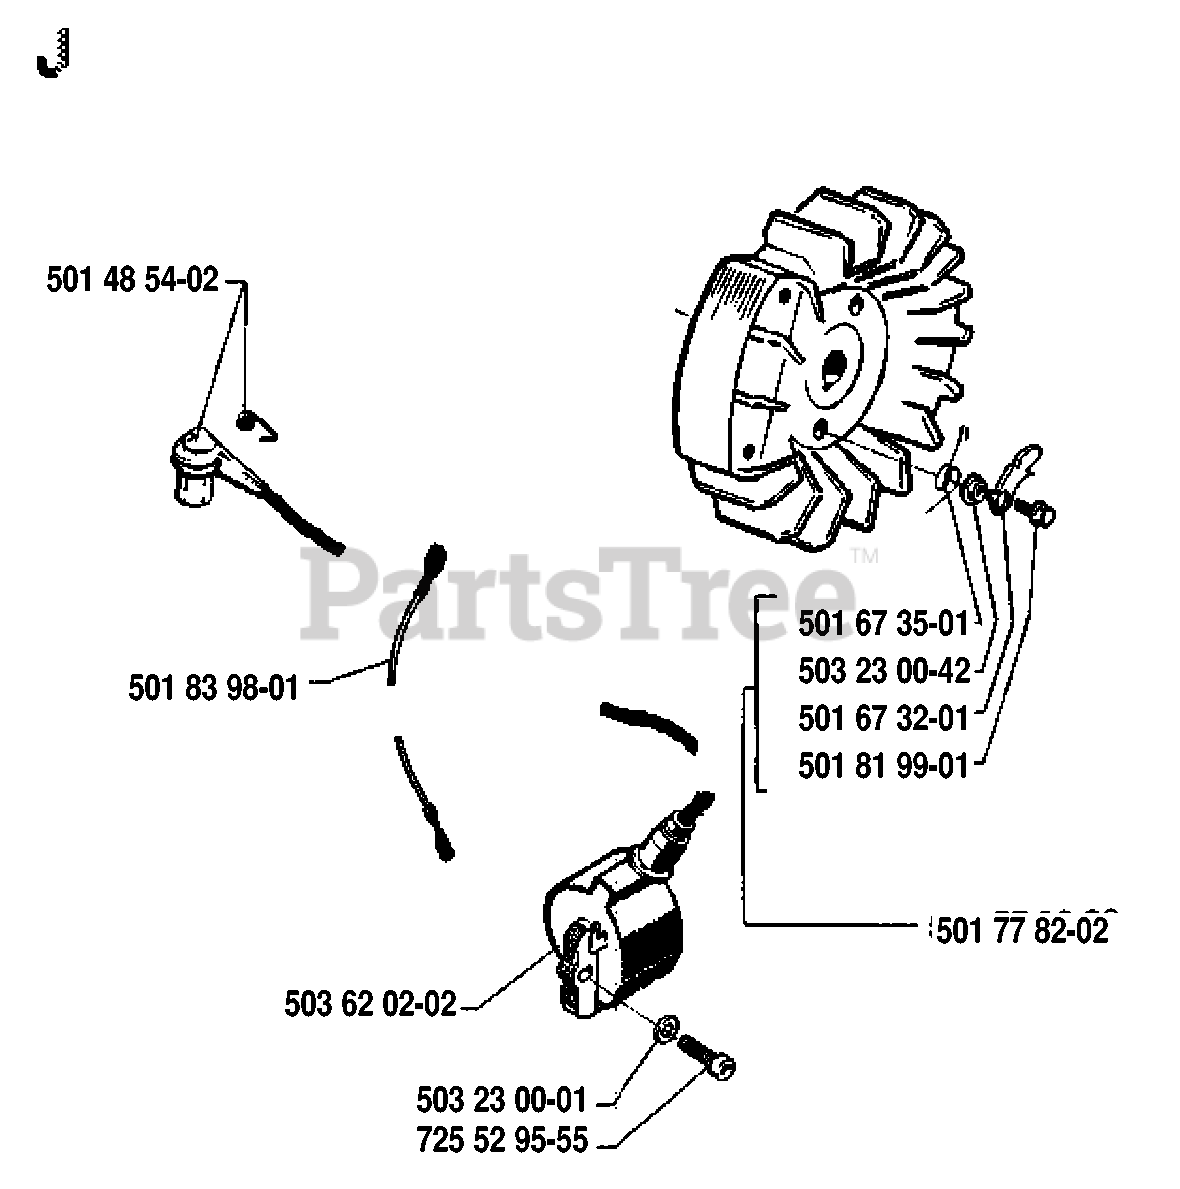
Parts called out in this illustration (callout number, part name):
1	PLUNGER.ASM.LIFT.LEVER.BLK.
2	SHAFT.ASM.LIFT.YT
3	PIN.GROOVE.5/16
4	RETAINING RING LT
6	BEARING.NYLON
7	GRIP HANDLE
8	PLUNGER BUT KIT
11	LINK LIFT LH
12	LINK LIFT RH
13	RETAINER-SPRNG RB
15	LINK.SUSPENSION.FRONT
16	NUT.HEX.JAM.1/2-13
18	NUT.LK.W/WSH.1/2.
19	ARM.REAR.SUSPENSION
20	PIN.COTTER.7/16.BOW TI.
26	RETAINER CLIP
27	ROD ADJ LIFT
28	NUT
29	KNOB INF 3/8-16
31	BEARING.PIVOT.LIFT
32	NUT CROWNLOCK 3/8-24
36	POINTER, HEIGHT INDICATOR(2 2)
38	SCREW 5/16-18X1
41	HEIGHT INDICATOR
49	NUT
50	NUT PUSH M
